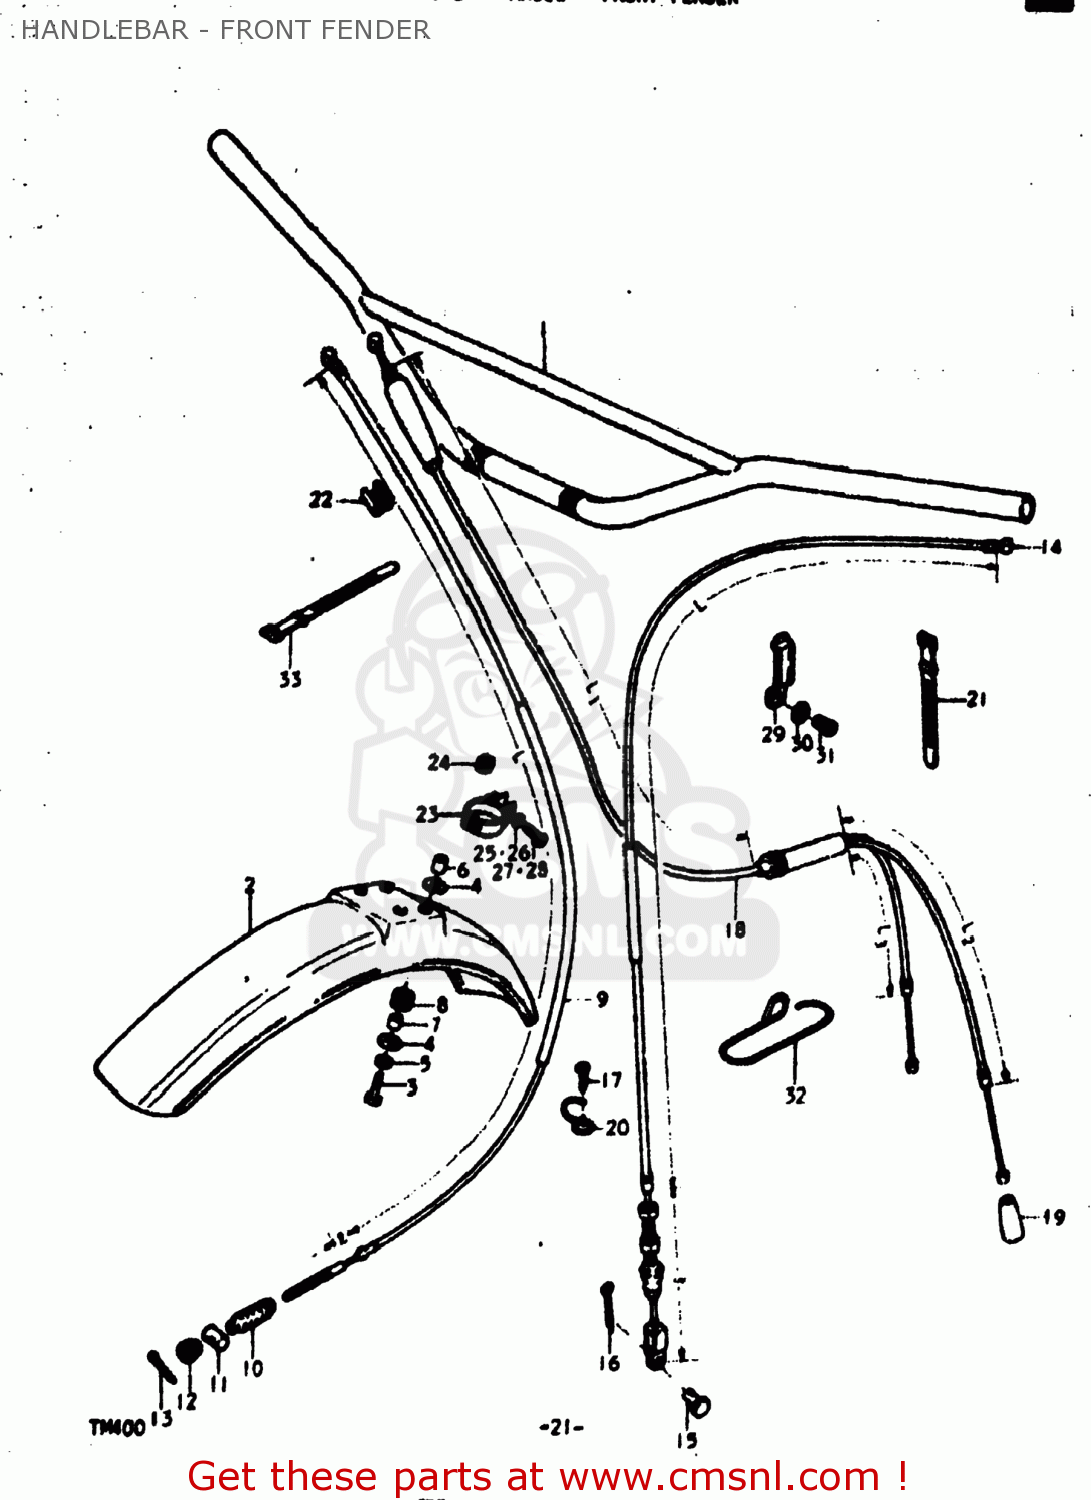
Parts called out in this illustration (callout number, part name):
1	HANDLEBAR
2	FENDER,FRONT
3	BOLT
4	WASHER (6.5X24X1.2)
5	LOCK WASHER
6	SPACER
7	SPACER (6.5X10.5X13.5)
8	CUSHION
9	CABLE ASSEMBLY,FRONT BRAKE
10	SEAL,DUST
11	PIN
12	NUT
13	PIN
14	CABLE ASSEMBLY,CLUTCH
15	PIN(L:15)
16	PIN
17	SCREW
18	CABLE ASSEMBLY,THROTTLE
19	SEAL,DUST(7X18X30)
20	GUIDE,CABLE
21	CLAMP
22	CLIP
23	GUIDE,CABLE
24	CUSHION
25	LOCK WASHER
26	WASHER
27	SCREW
28	SCREW
29	CLAMP
30	LOCK WASHER
31	SCREW
32	GUIDE,CABLE
33	CLAMP
